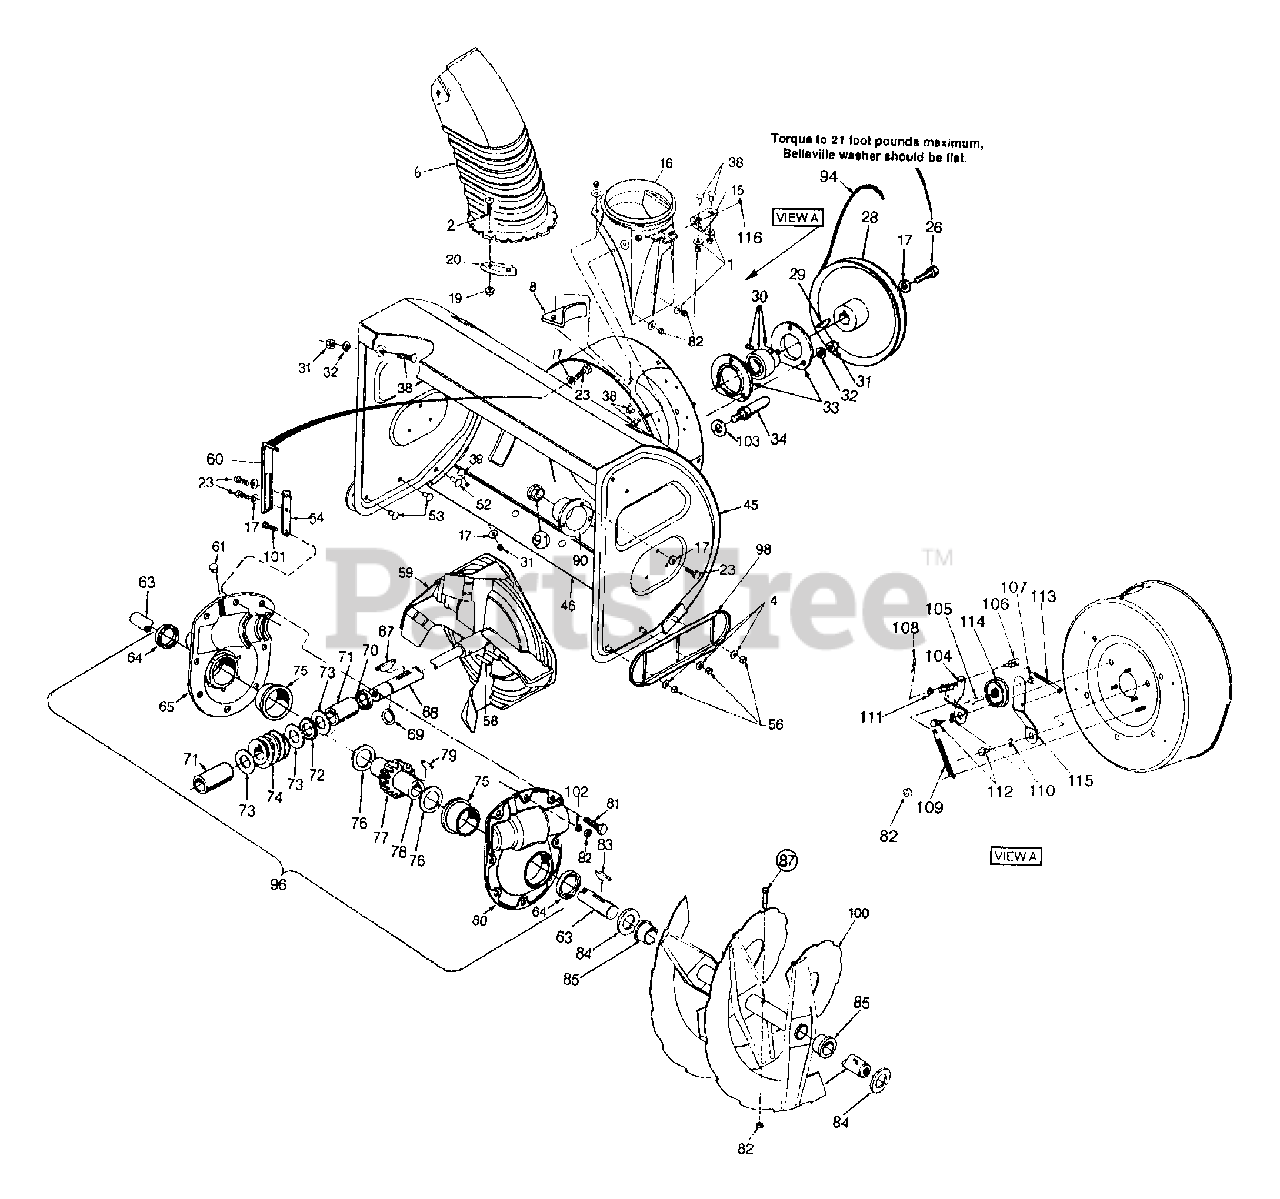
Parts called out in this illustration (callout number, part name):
1	Flat Washer .344 ID x .875 OD
2	Truss. Hd. Mach. Scr. 1/4-20 x .75
4	Belleville washer
6	6" Lower Chute Remote Tilt
16	Chute Adapter
17	Bell. Washer .345 ID x .88 OD x .06
19	Hex Cent. L-Nut 1/4-20 w/ Flange
20	Chute Flange Keeper
23	Hex Wash HD Self-Tap Scr 5.16-18 x .75
26	Hex Screw 5/16-18 x .75
28	1/2" V-Pulley .875 ID x 10.12 OD
29	#9 Hi-Pro Key 3/16 x 3/4 Dia HT
30	Self-Aligning Bearing .875 ID
31	Hex Nut 5.16-18 GD. 5
32	L-Wash 5.16 ID
33	Bearing Housing
34	Belt Keeper Studs 3/8-16 x 2.75
38	Carriage Bolt 5.16-18 x .75
52	Carriage Bolt 3/8-16 x 1.00 Gr. 5
53	Carriage Bolt 3/8-16 x .75" Lg.
56	Hex Jam Nut 3/8-16
58	Spring Spiral Pin Heavy- 5/16 dia x 1.7
61	Barbed Plug
63	Spiral Axle -33"
64	Oil Seal 1.50 ID Garlock (76 x 6223)
65	Gear Housing Half - RH
67	#9 Hi-Pro Key 3/16 x 3/4 dia HT
68	Auger Drive Shaft
69	Snap Ring for .875 dia. shaft
70	Oil Seal for .875 ID (76 x 6133)
71	Sleeve Bearing .875 ID
72	Thrust Bearing .88 ID x 1.44 OD x .078
73	Flat Washer .88 ID x 1.4 OD x .125
74	Worm Gear LH Double Thread
75	Flange Brg. 1.5 ID x 1.75 OD x .80
76	Flat Washer 1.5 ID x 2.0 OD x .03
77	Worm Gear LH Double Thread (Bronze)
78	Worm Gear Shaft
79	#91 Woodruff Key 1/4 x 3/4 dia
80	Gear Housing Half LH
81	Hex Flange Scr. 5/16-18 x .75
82	Hex Ins. L-Nut 5/16-18
83	#91 Woodruff Key 1/4 x 3/4 dia
84	Flat Washer
85	Flange Bearing
87	Shear Bolt 5/16-18 x 1.75
91	Flange Bearing w/flats
94	V-Belt 1/2 x 44 LG
96	Worm Gear Box Ass'y
102	5/16 Sprg Wash
103	3/8 Sprg Lock Wash
104	Brkt Ass'y; Brkt
105	Scr Hex Cap 3/8-24 x 1.5 GRD 5
106	Adjustment Ferrule
107	Hex Ins L-Nut 3/8-24
108	Intern Cot-Pin 5.16 dia
109	Spr Extn .470 dia x 4.75 Lg
110	Wave Washer .66 ID x .88 OD
111	Fl-Wash SAE .34 x .68 x.
112	Shld Scr .625 dia x .170 x .062
113	Rod Idler Auger
114	3.0 OD Flat Idler with Flanges
116	Plastic Bushing .380 ID
